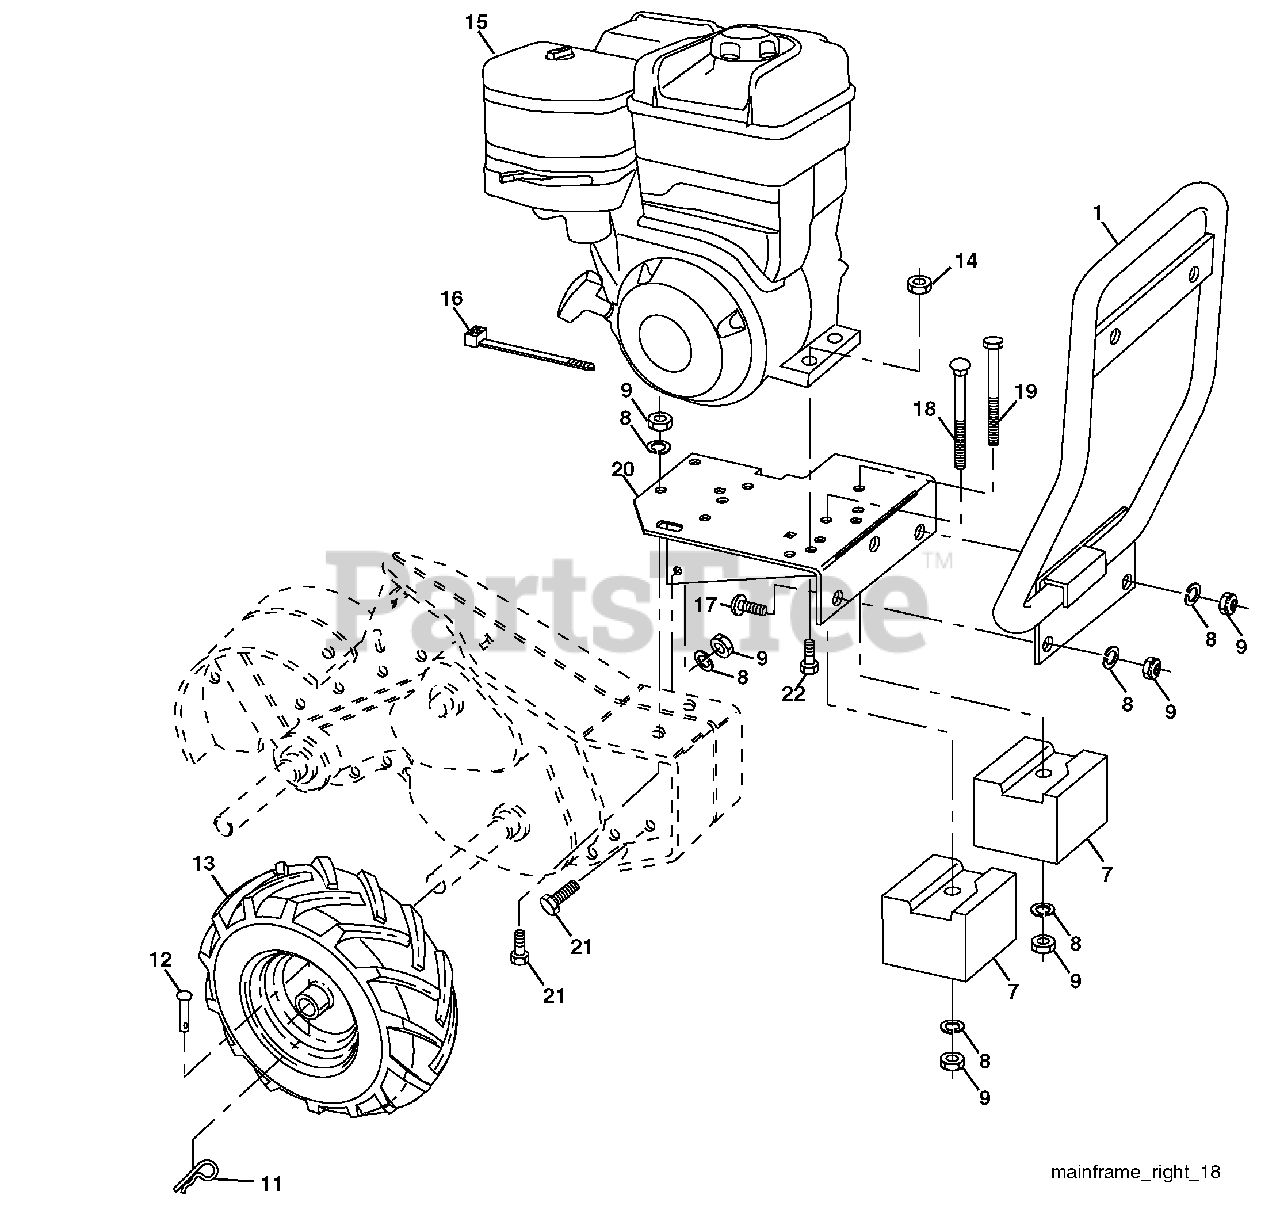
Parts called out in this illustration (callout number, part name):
1	Bumper
7	Counter Weight, R.H.
8	Washer, Lock 3/8
9	Nut, Hex 3/8-16
11	Clip, Hairpin
12	Rivet, Drilled
14	Nut, Lock Hex Flange
16	Tie Cable
17	Bolt, Hex 5/16-18 x 1-1/2
18	Bolt 3/8-16 x 4-1/2
19	Bolt Hex 3/8-16 x 4-1/2
20	Base Engine
21	Bolt, Hex 5/16-18 x 1
22	Bolt Hex Hd 5/16-18 x 1-1/2
